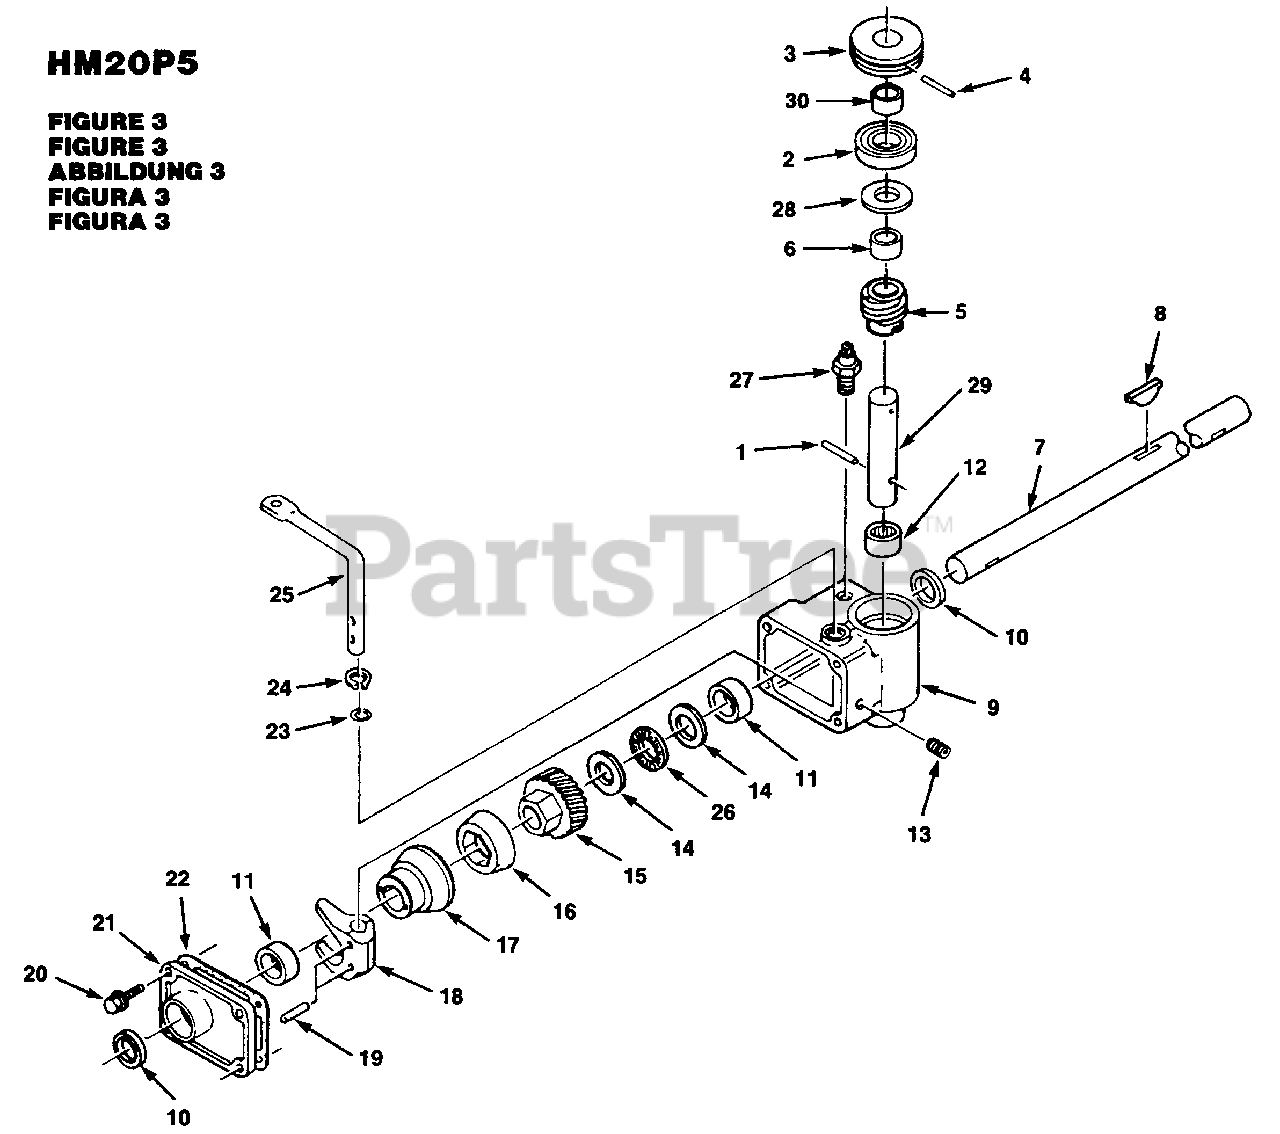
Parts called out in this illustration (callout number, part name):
2	4BALL BEARING-TBO
3	Pulley - drive
4	Pin - Roll 3/32 x 1 1/4"
5	WORM & SPACER
6	SPACER - Worm
7	SHAFT-Drive
9	HOUSING - Gear box
11	BUSHING TBO
12	BEARING,NEEDLE TBO
13	PLUG - Pipe
16	CONE - Friction
17	DRUM - Clutch
19	PIN - Groove
20	SCREW- 1/4-20 x 7/8
21	COVER - Gear Box
22	GEARBOX GASKET
24	TRU-ARC RING
25	LEVER - Shift
26	BEARING - Needle
29	WORM- Shaft
30	SPACER- Pulley
